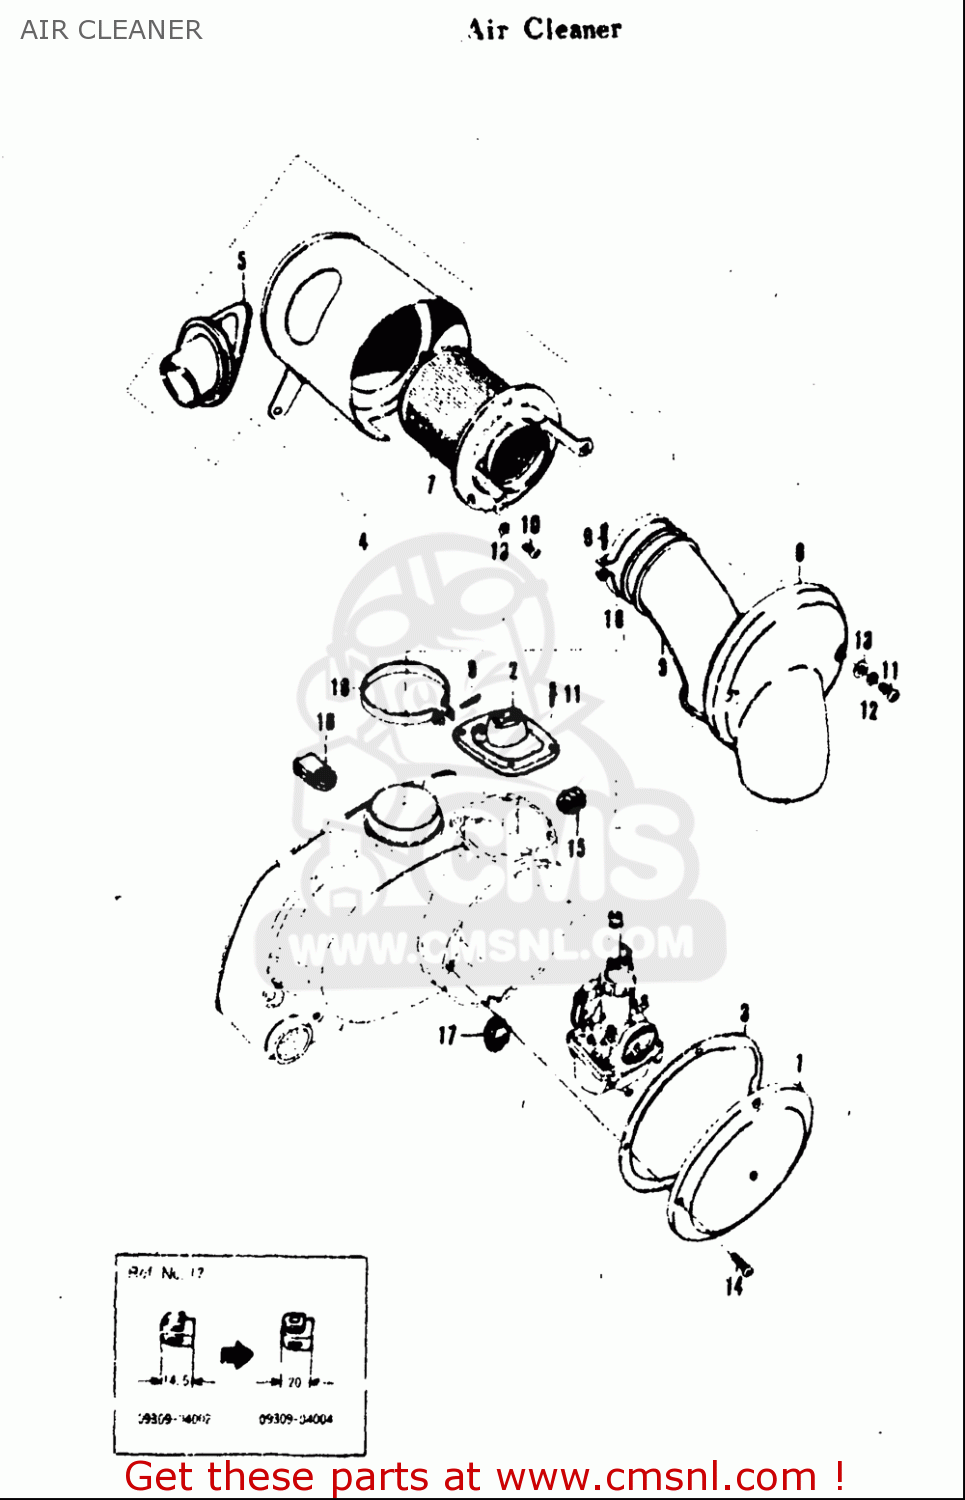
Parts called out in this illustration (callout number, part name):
2	COVER,CARBURETOR TOP
5	PIPE,AIR CLEANER INLET
7	FILTER ASSY
9	SCREW 4X16
11	SCREW
12	WASHER,LOCK
13	WASHER
14	SCREW(5X14)
15	Plug
16	GROMMET
17	GROMMET
